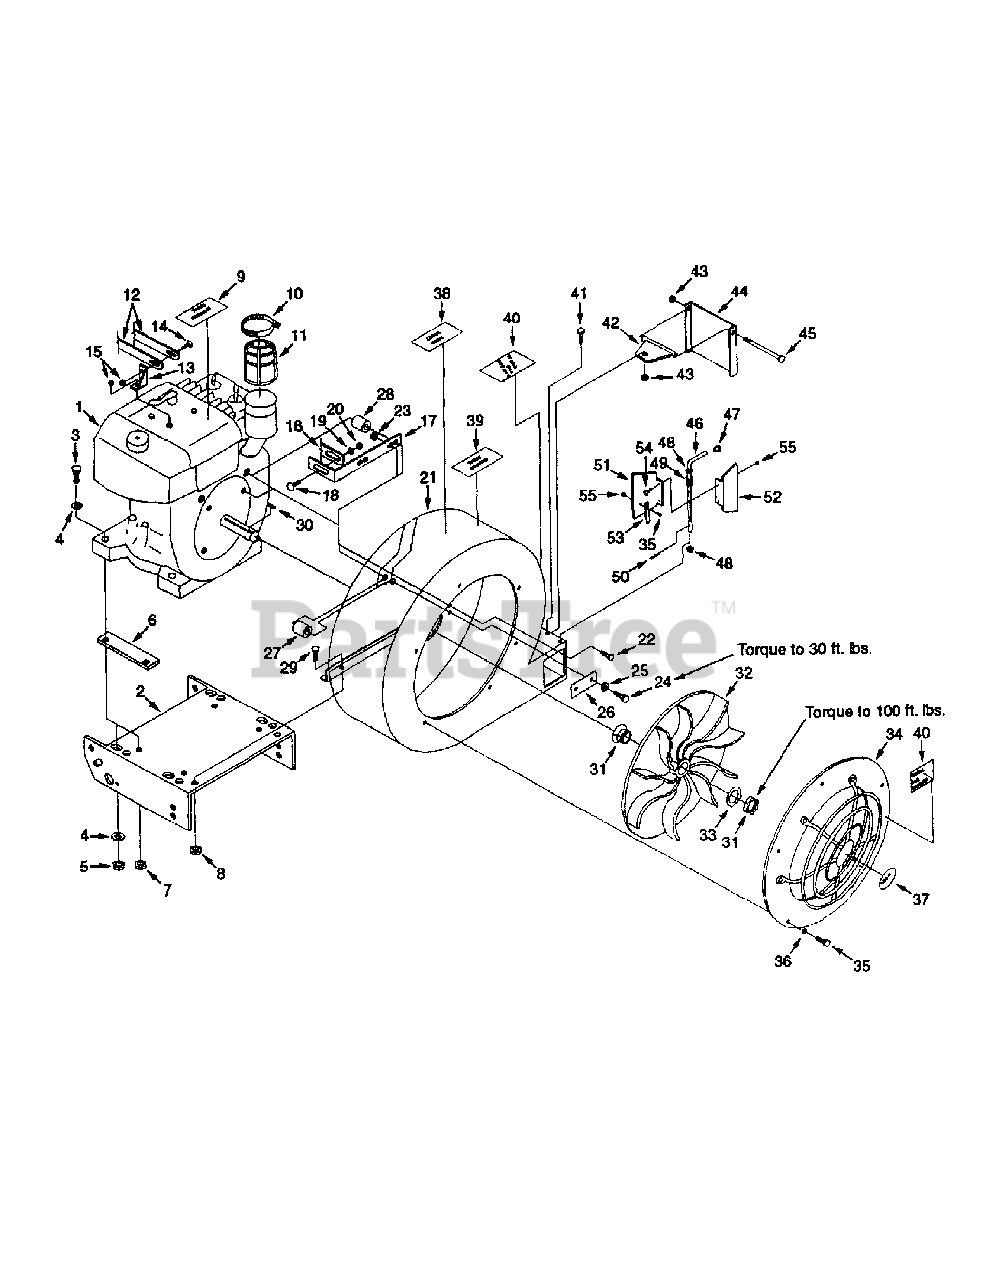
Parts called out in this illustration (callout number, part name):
1	Engine, 8hp Briggs & Stratton I/C
2	Base Plate, Engine
3	Cap Screw, 5/16-18 x 1-3/4 Hex Head
4	Flat Washer, 5/16 SAE
5	Hex Nut, 5/16-18 Side Lock
6	Riser Plate, Engine
7	Hex Nut, 5/16-18 Side Lock
8	Hex Nut, 5/16-18 Side Lock
9	Decal Warning Label
10	Clamp, Muffler Guard
11	Muffler Guard
12	Center Brace, Offset
13	Pivot, Center Brace
14	Carriage Bolt, 5/16-18 x 3/4
15	Hex Nut, 5/16-18 Side Lock
16	Center Brace
17	Center Support
18	Carriage Bolt, 5/16-18 x 3/4
19	Flat Washer, 5/16 SAE
20	Hex Nut, 5/16-18 Side Lock
21	Fan Housing
22	Cap Screw, 3/8-16 x 1 Hex Head
23	Hex Nut, 3/8-16 Stover Lock
24	Cap Screw, 3/8-16 xd 1-1/2 Hex Head
25	Lock Washer, 3/8
26	Strap, Housing Lock
27	Housing Spacer
28	Spacer
29	Cap Screw, 5/16-18 x 3/4 Hex Head
30	Key, 1/4 x 1/4 x 1-1/8
31	Fan Bushing/Hex Nut
32	Fan
33	Lock Ring, Fan Bushing
34	Front Guard
35	Machine Screw, #8-32 x 3/8 Round Head
36	Lock Washer, #10 External Tooth
37	Decal, Stop First/Then Lift
38	Decal, MTD
39	Decal, Caution Procedure
40	Decal, Danger Fan
41	Cap Screw, 1/4-20 x 3/4 Hex Head
42	Hinge Bracket
43	Hex Nut, 1/4-20 x 3/4 Hex Head
44	Deflector Plate
45	Cap Screw, 1/4-20 x 5 Hex Head
46	Handle, Front Door
47	Crutch Tip
48	Brass Bushing
49	Spring, Deflector
50	Cotter Pin, 3/32 x 3/4
51	Plate, Deflector Inside
52	Plate, Deflector Outside
53	Latch, Front Door
54	Machine Screw, #8-32 x 3/4 Round Head
55	Hex Nut with Washer, #8-32
